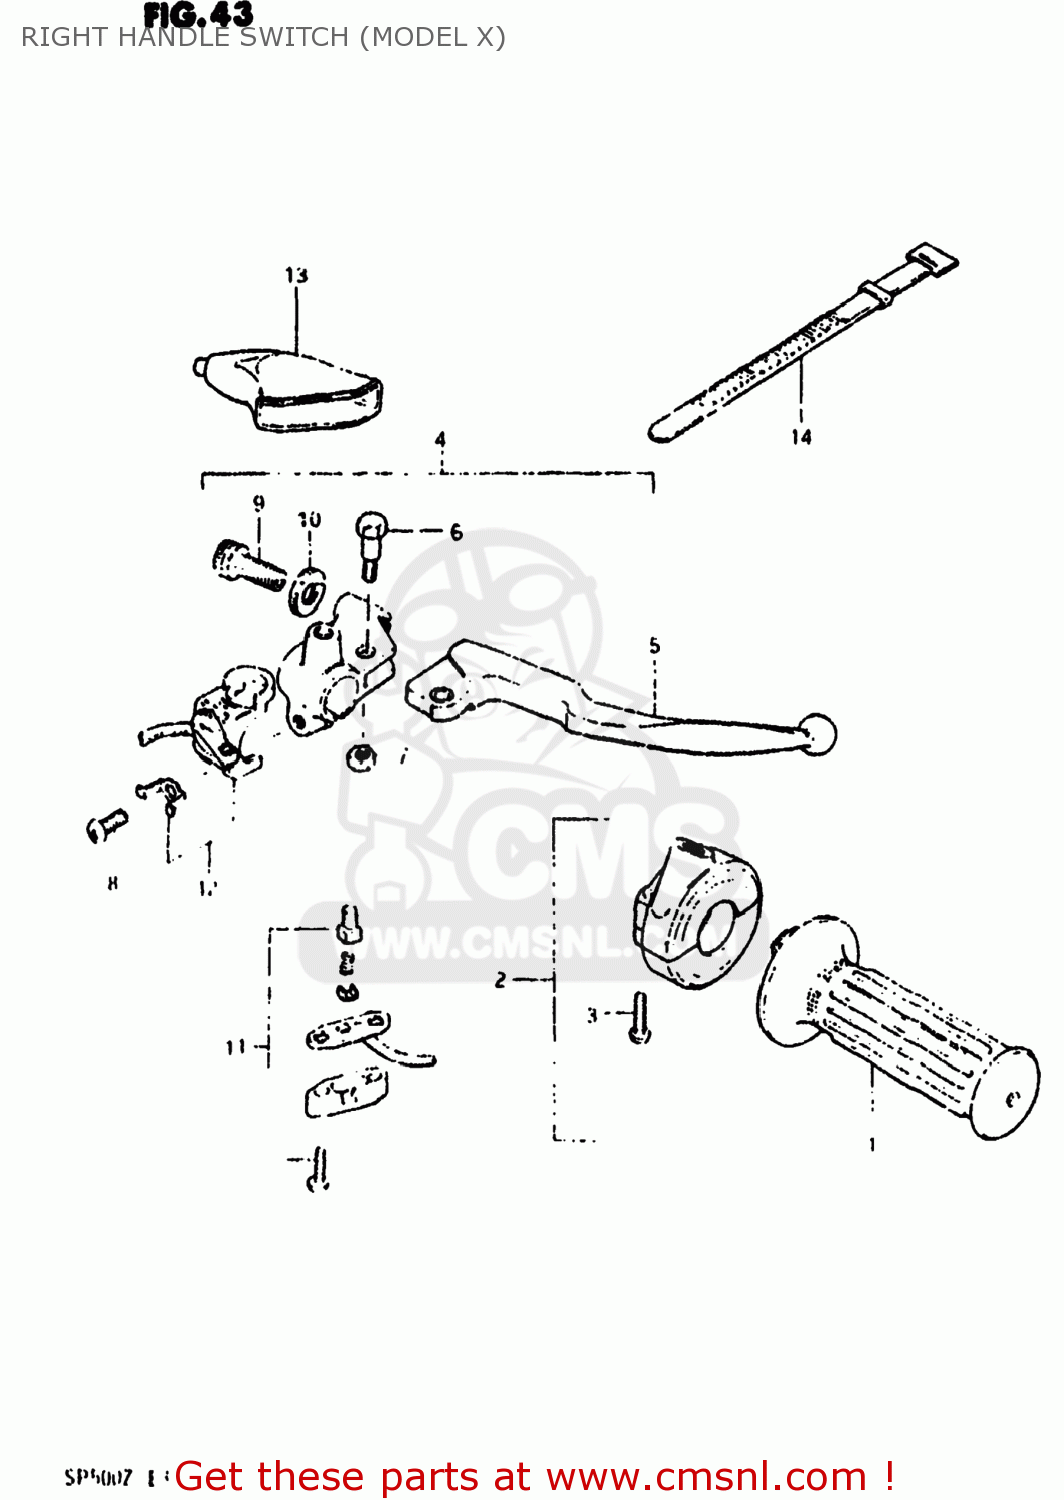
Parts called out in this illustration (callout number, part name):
1	CASE ASSEMBLY,THROTTLE
2	CASE ASSY,THROTTLE
3	SCREW 5X20
4	LEVER ASSEMBLY,BRAKE
5	LEVER,BRAKE
6	BOLT,LEVER
7	NUT 6MM
8	SCREW
9	ADJUSTER,CABLE
10	NUT,CABLE ADJUSTER
11	SWITCH ASSEMBLY
12	SWITCH ASSY,ENGINE STOP
13	COVER,CLUTCH LEVER
14	CLAMP
